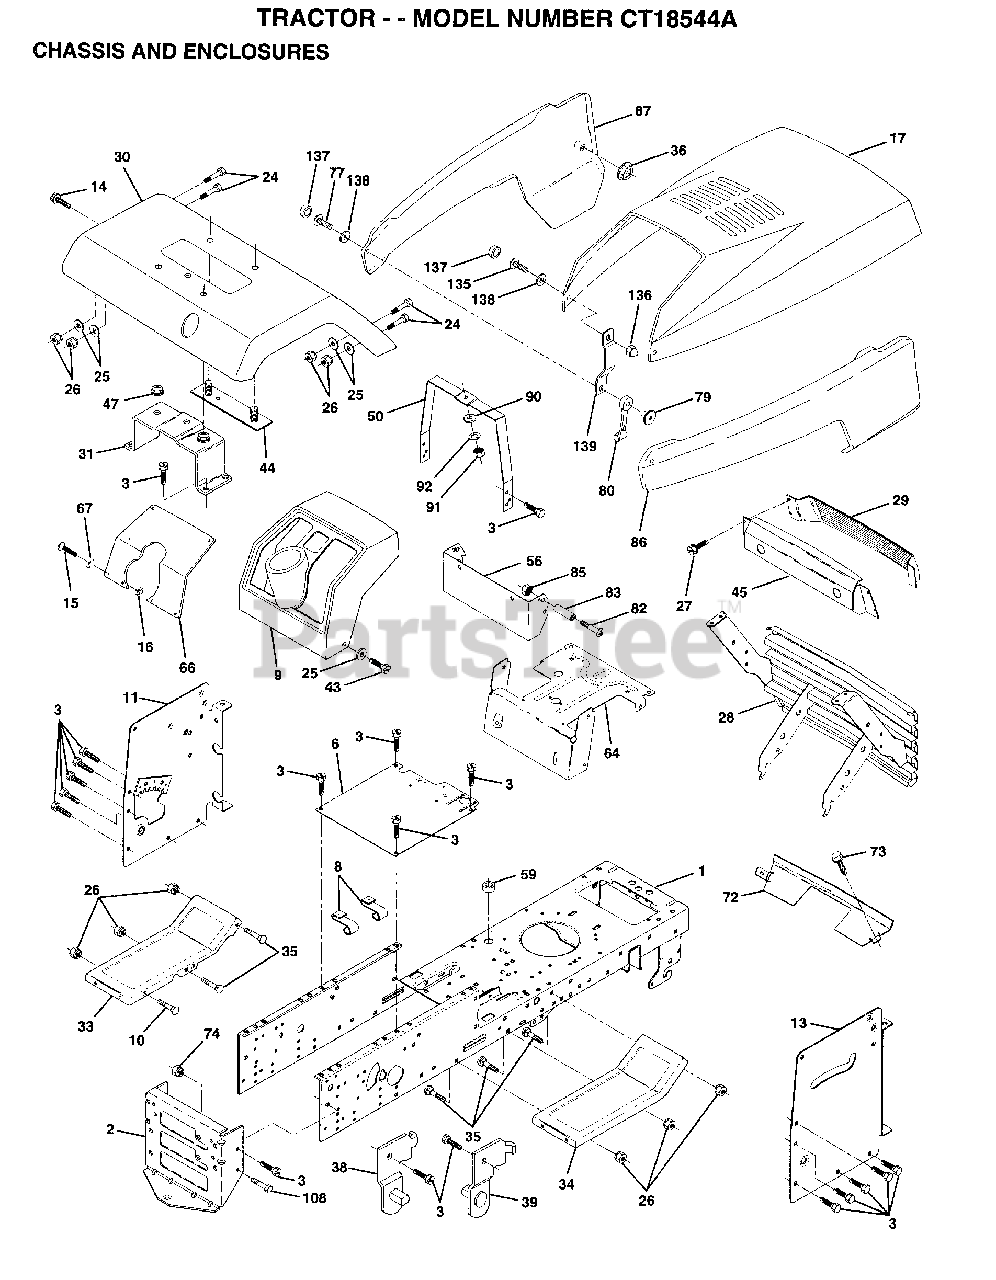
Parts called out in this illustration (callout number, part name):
1	CHASSIS.WLD.11GA
3	SCREW
8	"CLIP,INSULATOR"
9	DASHBOARD BLACK
11	PANEL.DASH.LH.PNT
13	PANEL.DASH.RH.PNT
14	SCREW LT
15	SCREW
17	HOOD PNT YARDPRO
24	BOLT
25	WASHER
26	NUT
28	GRILLE ASM PNT
29	LENS.BAR.CLEAR
31	BRKT.ASM.FENDER
33	FOOTREST.LH.LT/GT
34	FOOTREST.RH.LT/GT
35	BOLT
36	PAL NUT LT
38	BRACKET ASM LH
39	BRACKET ASM RH
43	SCREW
44	STRAP ASM FENDER
45	BEZEL.ASM.
47	NUT-PUSH YT
50	DASH.SUPT.YP/HUSQ
56	EXT DASH LTYT
64	DASH.LOWER.LT
66	PLATE SLKSCR YP
67	WASHER
72	STRAP.PNT.GRILLE
73	SCREW CRT
77	SCREW
79	WELDNUT
80	HOOD LATCH T
82	SCREW
83	SPACER LT
86	PANEL PNT RH SIDE
87	PANEL PNT LH SIDE
90	WASHER PM
92	LOCKWASHER
135	SCREW.10-24X3/8.
136	ACORN NUT RB
137	SNAP CAP LT
138	CAP WASHER SNAP NAT
139	BKT.SPT.HOOD/PANL
